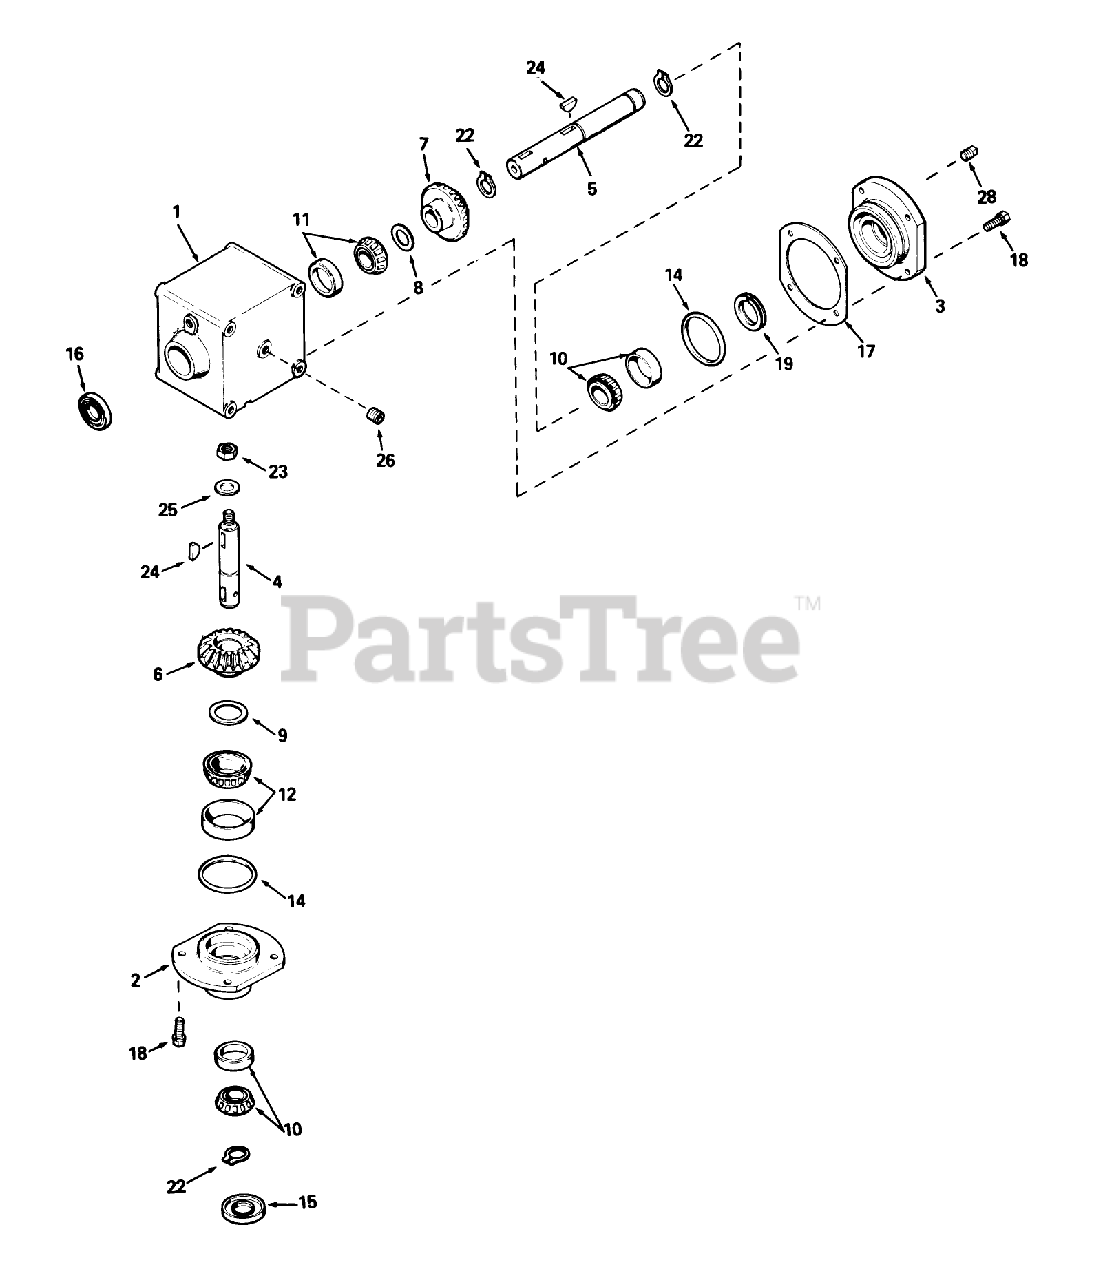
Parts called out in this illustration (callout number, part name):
1	Housing
2	Cap-Retainer
3	Cap-Retainer
4	Shaft-Input
5	Shaft-Output
6	Gear-Bevel 25T
7	Gear-Bevel 26T
8	Shim (1.5" OD x 1.016" ID x .002")
9	Shim (2" OD x 1.531" ID x .002")
10	Bearing Cup Assembly
11	Bearing Cup Assembly
12	Bearing Cup Assembly
14	ORing
15	Seal-Oil
16	Seal-Oil
17	Shim-Oil
18	Screw-Hex Hd.
19	Ring-Load
22	Ring-Retaining
23	Jam Nut
24	Key-Woodruff
25	Washer-Flat
26	Plug-Pipe
28	Plug-Pipe
